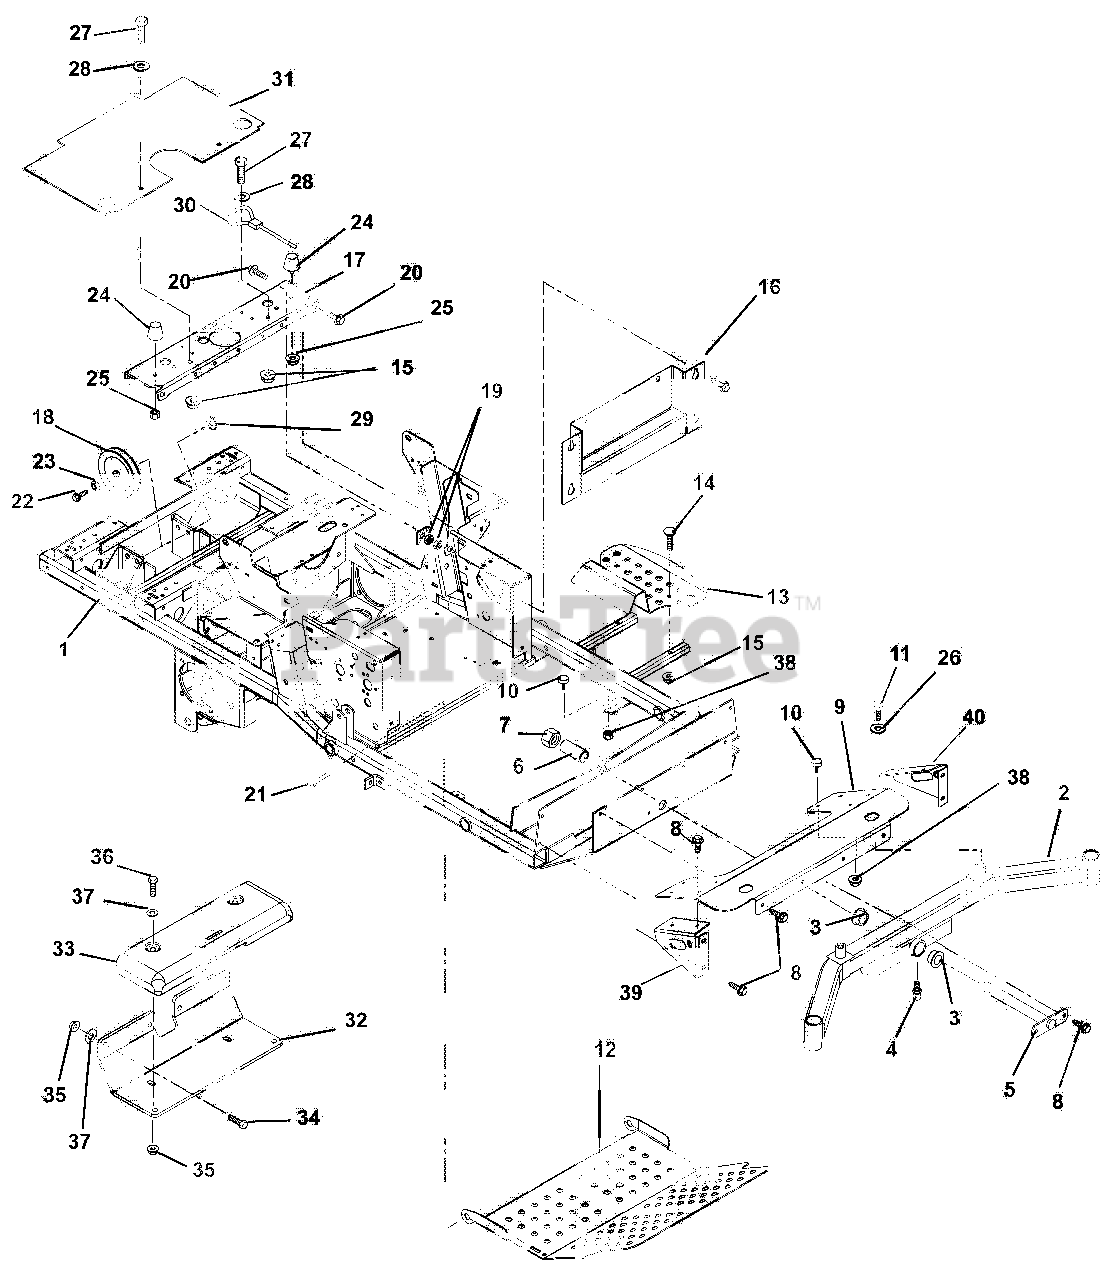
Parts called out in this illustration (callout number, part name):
1	Weldment, Frame
2	Weldment, Front Axle
3	Bushing, Flange 1.020 x 1.385 x .75 x 1.75
4	Fitting, Lube 45 Degree GM411031
5	Pin, Axle
7	Nut, Locking Nylon 1.0-14
8	Screw, Tapping .38-16 x .75
9	Axle Cover
10	Button, Bumper
11	Bolt, Hex .50-20 x 1.00 Grade 5
12	Panel, Inspection
13	Step, Ingress
14	Bolt, Round Head Square Neck .31-18 x 1.75 Grade 5
15	Nut, Locking Top Flange .31-18
16	Plate, Kick
17	Channel, Cross
18	Pulley, Idler
19	Nut, Retainer .375-16 x .37
20	Bolt, Serrated Flange Washer Head .38-16 x 1.00
21	Bolt, Hex .50-13 x 3.25 Grade 5
22	Bolt, Hex .50-13 x 2.25 Grade 5
23	Washer, Flat Steel .505 x .88 x .072
25	Nut, Spin Lock-Flange .312-18
26	Washer, Flat Steel .064 x 1.810 x .250
27	Bolt, Hex .31-18 X 1.00 Grade 5
28	Washer, Flat Steel .344 x 1.125 x .135
29	Nut, Locking Top Flange .50-13
30	Cable, Seat Prop
31	Guard, Grass
32	Bracket, Weight
33	Weight, Cast Iron
34	Bolt-Hex .50-13 x 1.00 Grade 5
35	Nut, Locking Top Flange .50-13
36	Bolt, Hex .50-13 x 4.50 Grade 5
37	Washer, Flat Steel .531 x 1.06 x .095
38	Nut, Spin Lock, Flange .312-18
39	Weldment, Right Hand Axle Cover Support
40	Weldment, Left Hand Axle Cover Support
